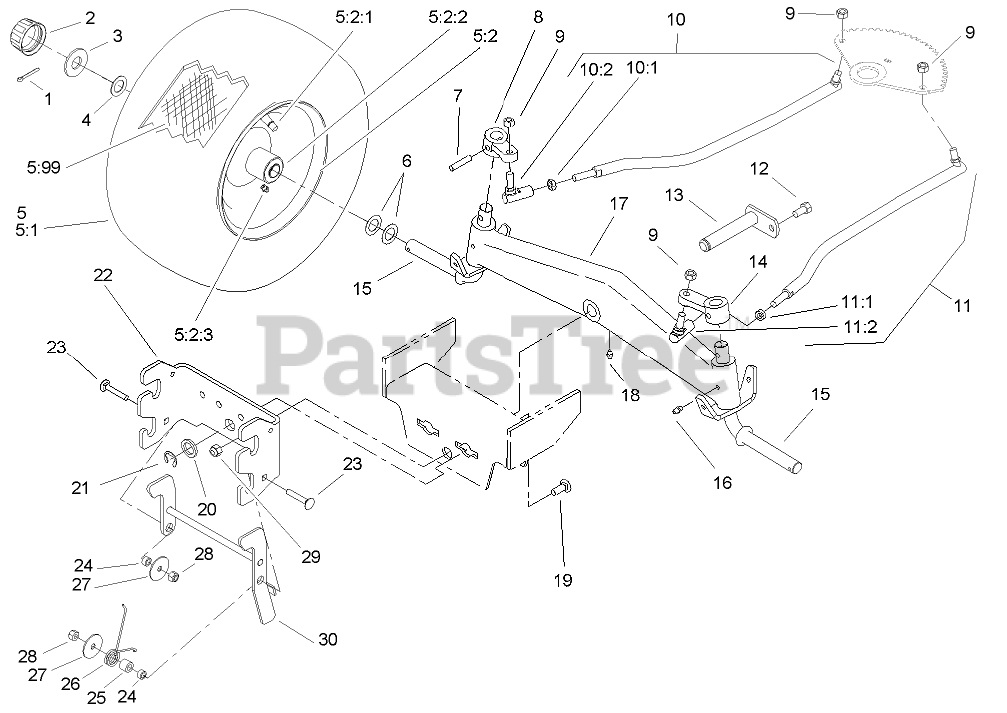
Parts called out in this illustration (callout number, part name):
1	PIN-COTTER
2	CAP-HUB
3	WASHER-PLAIN
4	WASHER
5	FRONT WHEEL and TIRE ASM
5:2	Wheel ASM
5:2:1	VALVE
5:2:2	BEARING-WHEEL
5:2:3	ZERK-GREASE
5:99	TUBE-INNER
6	WASHER-SHIM
8	ARM-SPINDLE, LH
10	LINKAGE-STEERING, RH
10:1	NUT-JAM
10:2	BALL-JOINT
11	LINKAGE-STEERING, LH
11:1	NUT-JAM
11:2	BALL-JOINT
12	SCREW-HWH, TAPTITE
13	PIN-AXLE
14	ARM-SPINDLE, RH
15	SPINDLE
16	FITTING-GREASE
17	AXLE-FRONT
18	FITTING-LUBE, 45 DEG
19	BOLT-CARR
20	Washer
21	E-RING
22	HITCH-FRONT
23	SCREW-CARR
24	SPACER-YOKE, RIGHT
25	SPACER-TUBE
26	SPRING-TORSION
27	WASHER-FLAT
28	NUT-LOCK, NI
29	NUT-LOCK, NI
30	LATCH ASM
